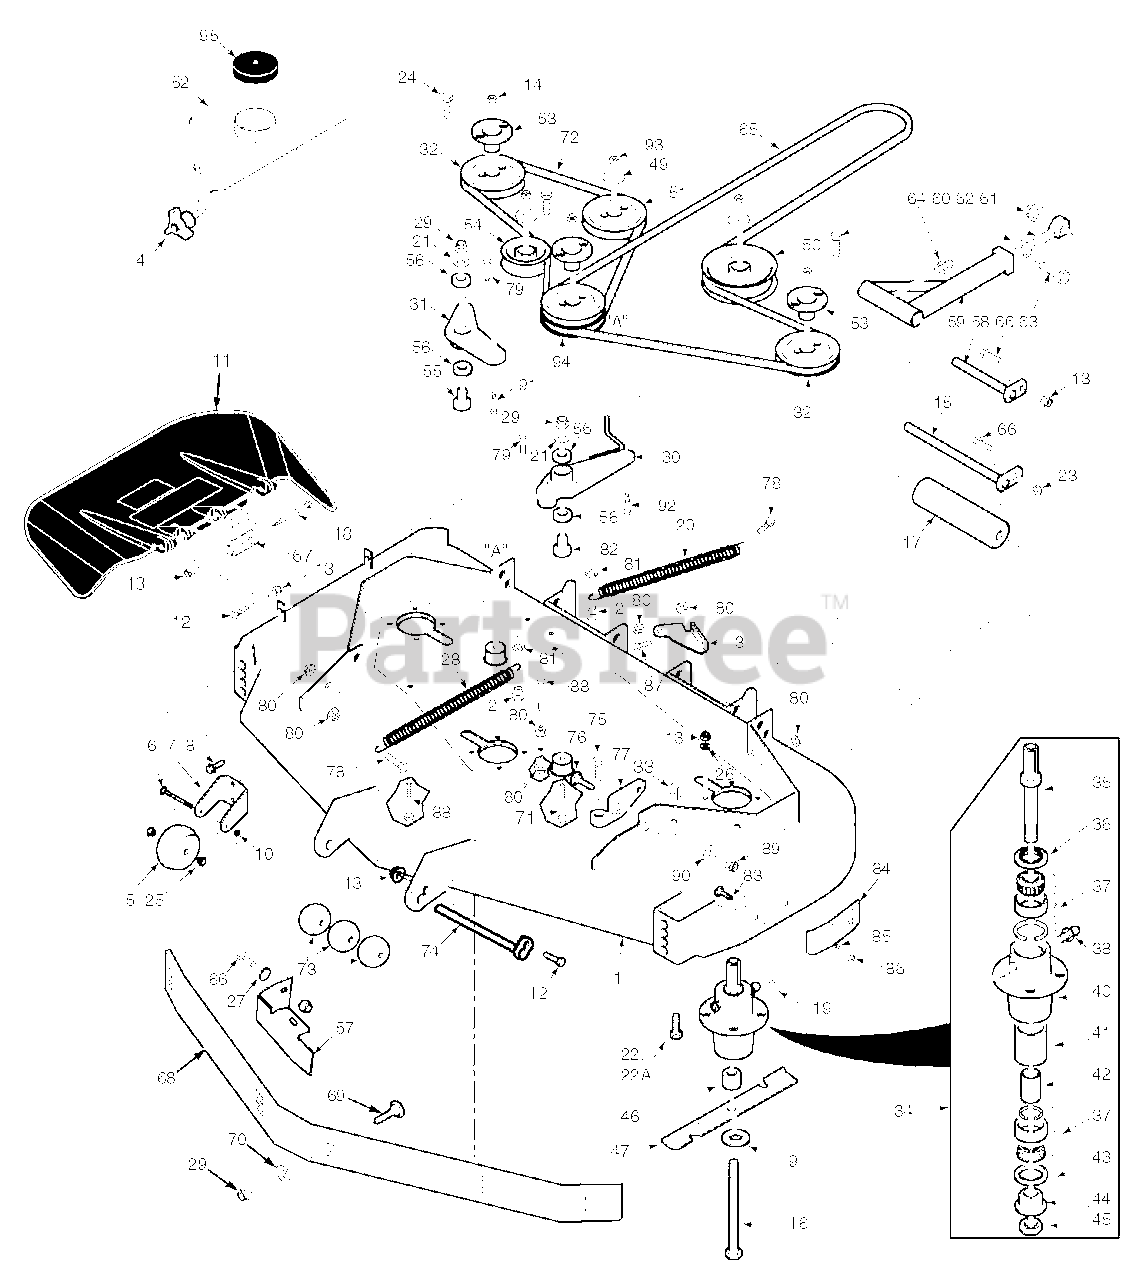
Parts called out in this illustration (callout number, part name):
1	Cutter Deck Velocity Plus
2	Boss, Spring Anchor
3	Bracket, LH Spring Anchor 61V
4	Wing Nut, 3/8-16
5	Anti-Scalp Wheel
6	Bolt, Carriage 3/8-16 x 4"
7	Bracket, Anti-Scalp Wheel
8	Bolt, Serrated Flange 3/8-16 x 1"
9	Flatwasher, 5/8" Hardened
10	Locknut, 3/8-16 Center Lock
11	Discharge Chute Assy.
12	Bolt, Hex Head 5/16-18 x 1-1/2", Rear
12	Bolt, Hex Head 5/16-18 x 1-3/4", Front
13	Nut, Elastic Stop 5/16-18
14	Nut, 5/8-11 UNC
15	Shaft, Roller
16	Bolt, Hex Head 5/8-11 x 9-1/2"
17	Roller, Rear
18	Bolt, Hex Head 5/16-18 x 4-3/4"
19	Key, 1/4 x 1/4 x 2"
20	Spring, LH Deck Drive
21	Flatwasher, 3/8" - .938 x .391 x .105"
22	Bolt, Hex Head 5/16-18 x 1-3/4"
23	Nut, Serrated Flange 5/16-18
24	Bolt, Hex Head 1/4-20 x 1"
25	Bushing, .376 ID Oilite
26	Lockwasher 5/16"
27	Flatwasher 5/16"
28	Spring, RH Deck Drive
29	Nut, Elastic Stop 3/8-16
30	Idler Arm Assembly, LH Drive
31	lder Arm Assembly, RH Drive
32	Pulley, Tapered Bore 6.33" Dia.
33	U-Nut, 3/8-16
34	Spindle Assembly
35	Shaft, Spindle
36	Seal Upper
37	Bearing Assembly
38	Grease Fitting
39	Valve, Grease Relief
40	Housing, Spindle
41	Spacer, Outside
42	Spacer, Inside
43	Seal, Lower
44	Bushing, Bottom
45	Nut, Special 1-1/16 - 18
46	Spacer, Spindle
47	Cutter Blade 21"
48	Pulley, Double Groove 6.33" Dia.
49	Dust Shield
50	Idler Pulley, 5" Dia.
51	Idler Pulley, 5" Dia.
52	Belt Cover (61V)
53	Hub, Tapered 1-1/8" Bore
54	Idler Pulley, 3-1/2" Dia.
55	Pivot, Idler
56	Bearing
57	Turbo Baffle, Bolt On
58	Push Arm Shaft
59	Push Arm
60	Nut, 5/8-18 UNF
61	Nut, Elastic Stop 5/8-11
62	Rod End, 5/8 Male RH Thread
63	Bolt, Hex Head 5/8-11 x 4-1/2"
64	Grease Fitting, 90 Degree
65	Belt, Deck Drive 61V
66	Bolt, Hex Head 5/16-18 x 1"
67	Spring, Discharge Chute
68	Baffle Custom-Cut, 61V (7-Position)
69	Bolt, Carriage 3/8-16 x 1"
70	Flatwasher, 3/8-.391 x .938 x .105"
71	Bolt, Hex Head 3/8-16 X 3-1/2"
72	Belt, Deck Drive RH
73	Wheel, Anti Scalp
74	Roller Shaft
75	Bolt, Special
76	Bolt, Carriage 7/16-14 x 1-1/4"
77	Lever Assy., Deck Level
78	Bolt, Hex Head 3/8-16 x 1-1/2" Gr.8
79	Bolt, Hex Head 3/8-16 x 1"
80	Nut, Serrated Flange 3/8-16
81	Lockwasher, 5/16"
82	Pivot, Idler Short
83	Bolt, Carr. 5/16-18 x 3/4"
84	Wear Pad
85	Flatwasher, 5/16-.344 x .688 x .065"
86	Nut, Center Lock 5/16"
87	Bolt, Hex Head 3/8-16 x 1"
88	Bolt, Hex Head 3/8-16 x 2-1/2"
89	Nut, Elastic Stop 7/16-14
90	Flatwasher, 7/16-.500 x 1.250 x .083"
91	Bolt, Hex Head 3/8-16 x 2-1/4"
92	Bolt, Hex Head 3/8-16 x 3"
93	Nut, Elastic Stop 3/8-16
94	Pulley, Double Groove 6.33" Dia.
95	Cap, Spindle
